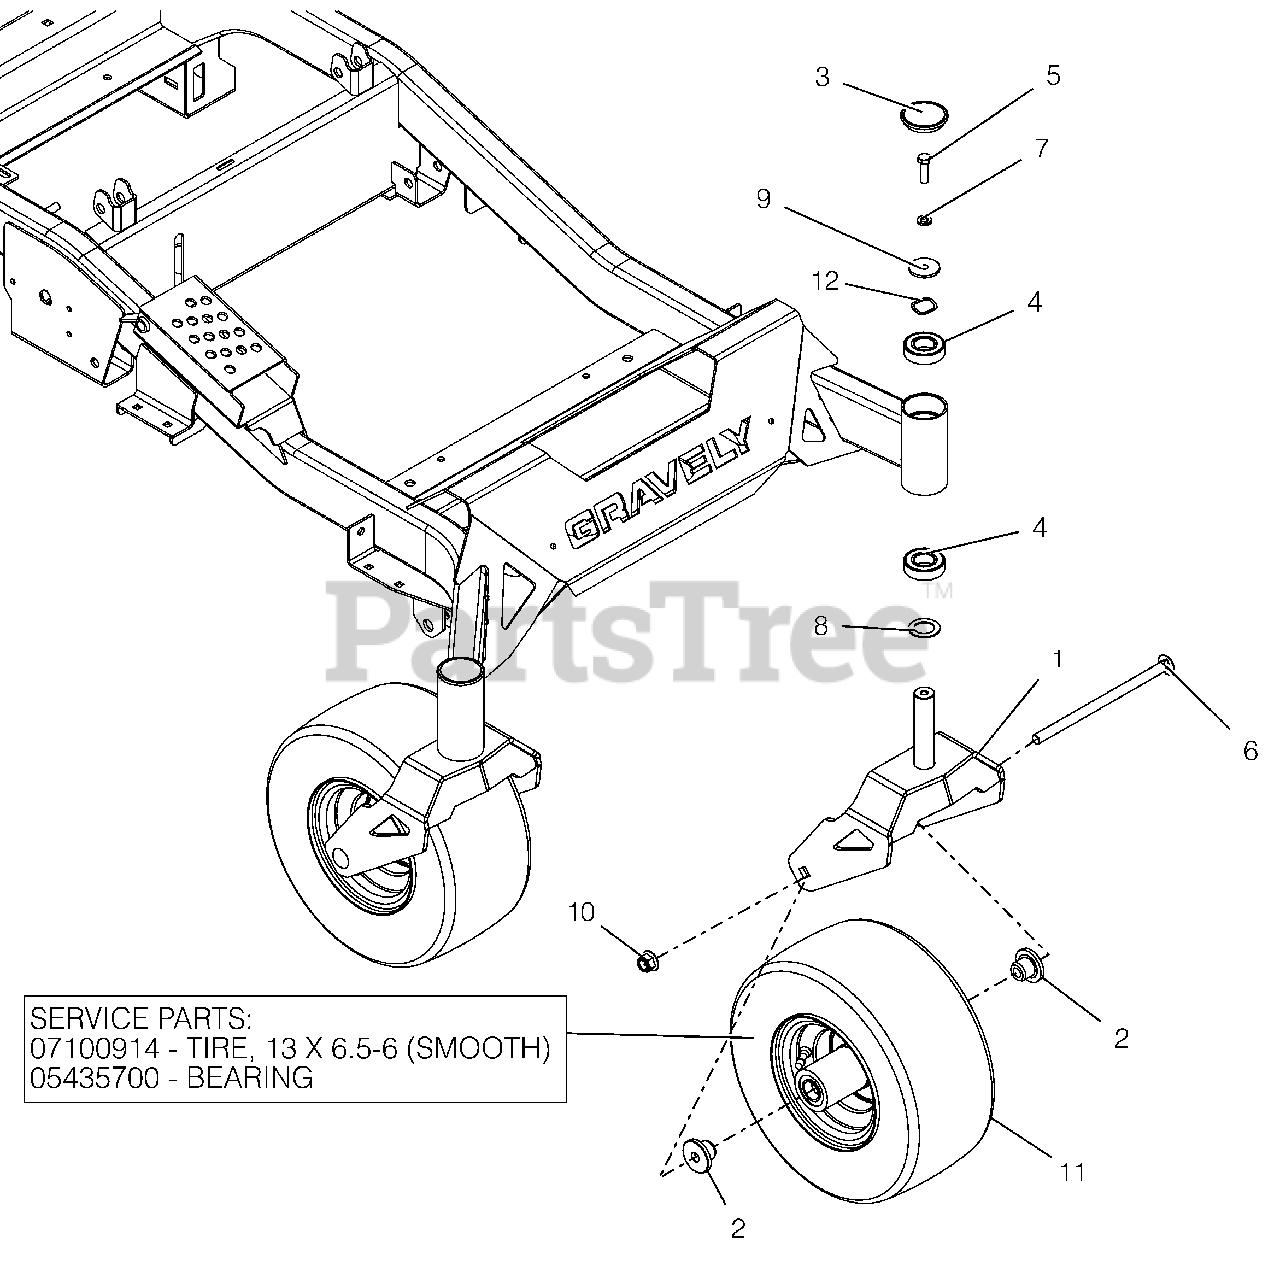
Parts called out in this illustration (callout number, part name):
1	WLDMT, HD CASTER FORK
2	SPACER, FRONT WHEEL
3	CAP, DUST
4	BRG,BALL 1.00X2.00X.563(1641)
5	@BLT-HEX .38-16X1.25 GR5 YWZC
6	BLT-RDHDSQNK .50-13X9.00 G5 Y
7	WSHR-LK .375X.115 HVY YWZC
8	WSHR-HRD-THRS 1.007X1.542X.062
9	WSHR-FL-STL .380X1.50X.125YWZC
10	@NUT-LK-NYL-FLG .50-13 YWZC
11	ASM, WHL/TIRE 13X6.50-6
11	TIRE, 13X6.50-6 SMOOTH
11	BRG, 25MM ID X 52MM OD X 15MM
12	WSHR-WAVE 1.0X1.25X.028 .145FH
